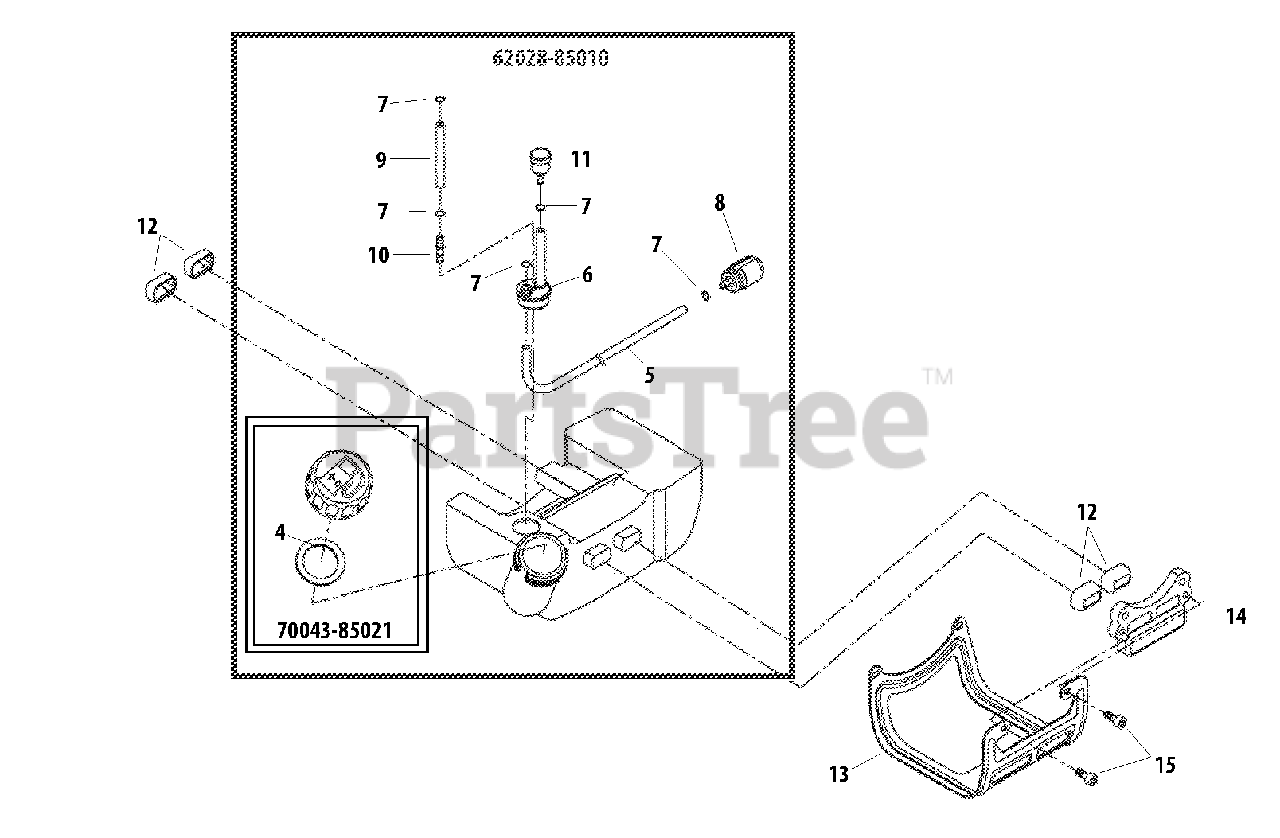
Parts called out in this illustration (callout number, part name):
4	GASKET, FUEL CAP
5	PIPE, FUEL
6	GROMMET, FUEL W/VENT PIPE
7	CLIP Ø6
8	FILTER, FUEL
9	PIPE, FUEL RETURN
10	CONNECTOR, PIPE
11	VENT ASSY
12	CUSHION, FUEL TANK
13	GUARD, METAL FUEL TANK
14	BRACKET, FUEL TANK
15	BOLT M5×12
62028-85010	TANK ASSY, FUEL
70043-85201	CAP ASSY, FUEL
